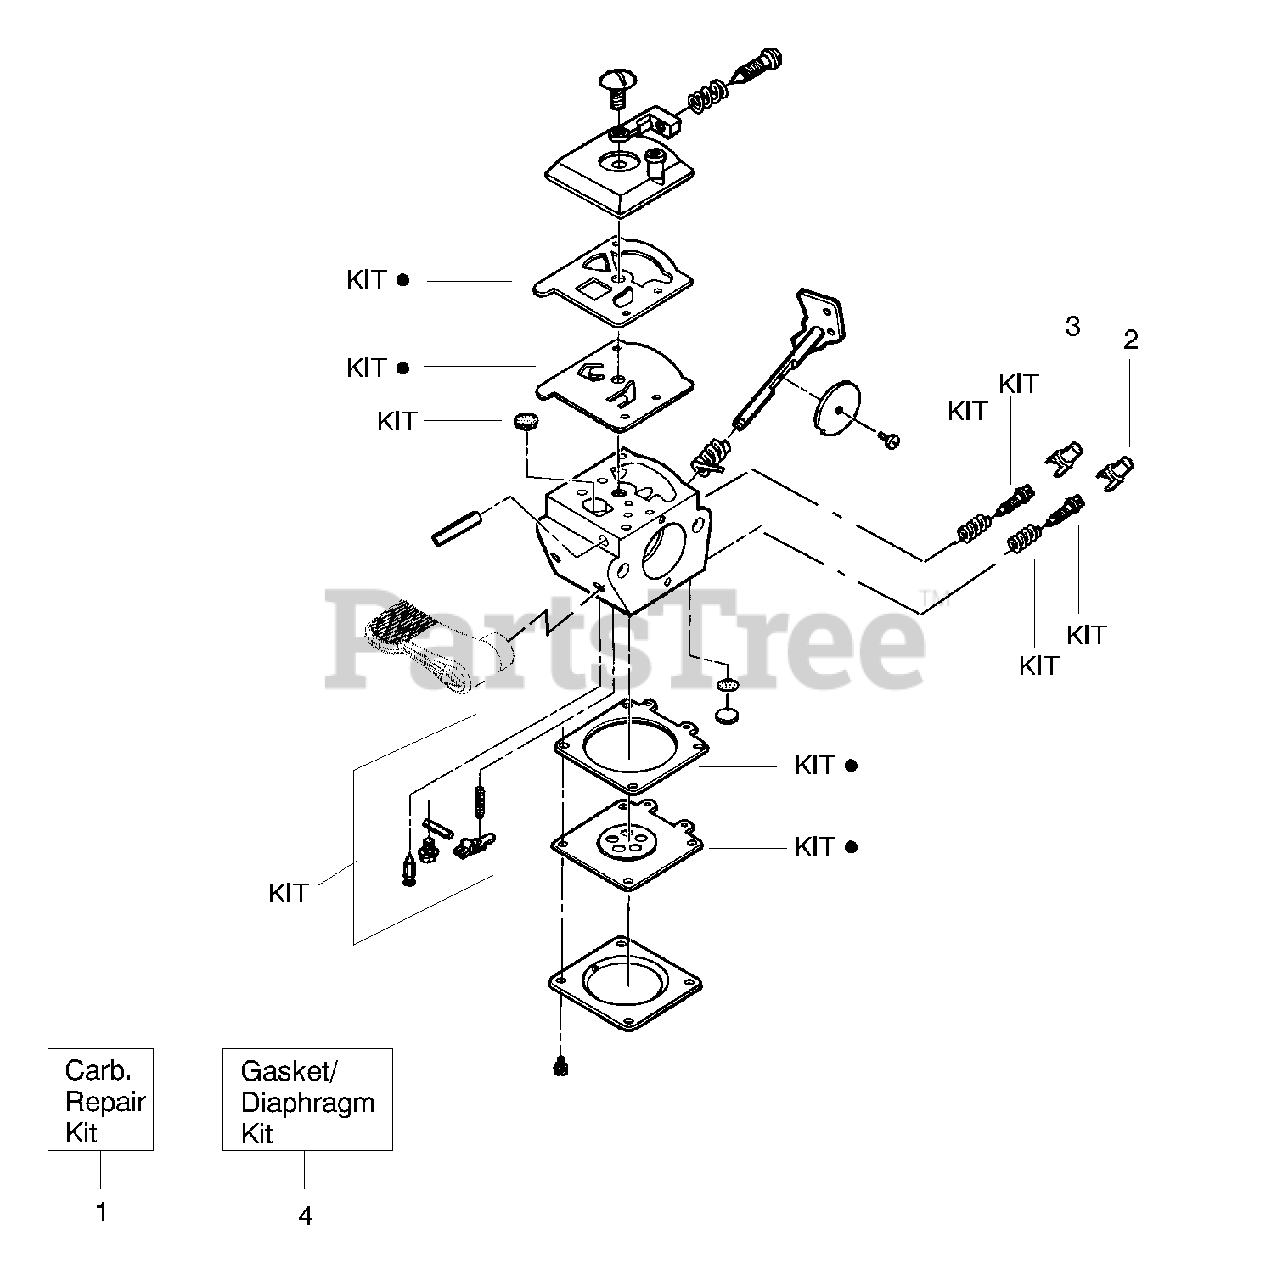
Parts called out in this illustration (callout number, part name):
1	Carburetor Repair Kit
2	Limiter Cap-Low (tan)
3	Limiter Cap-High (brown)
4	Gasket/Diaphragm Kit
